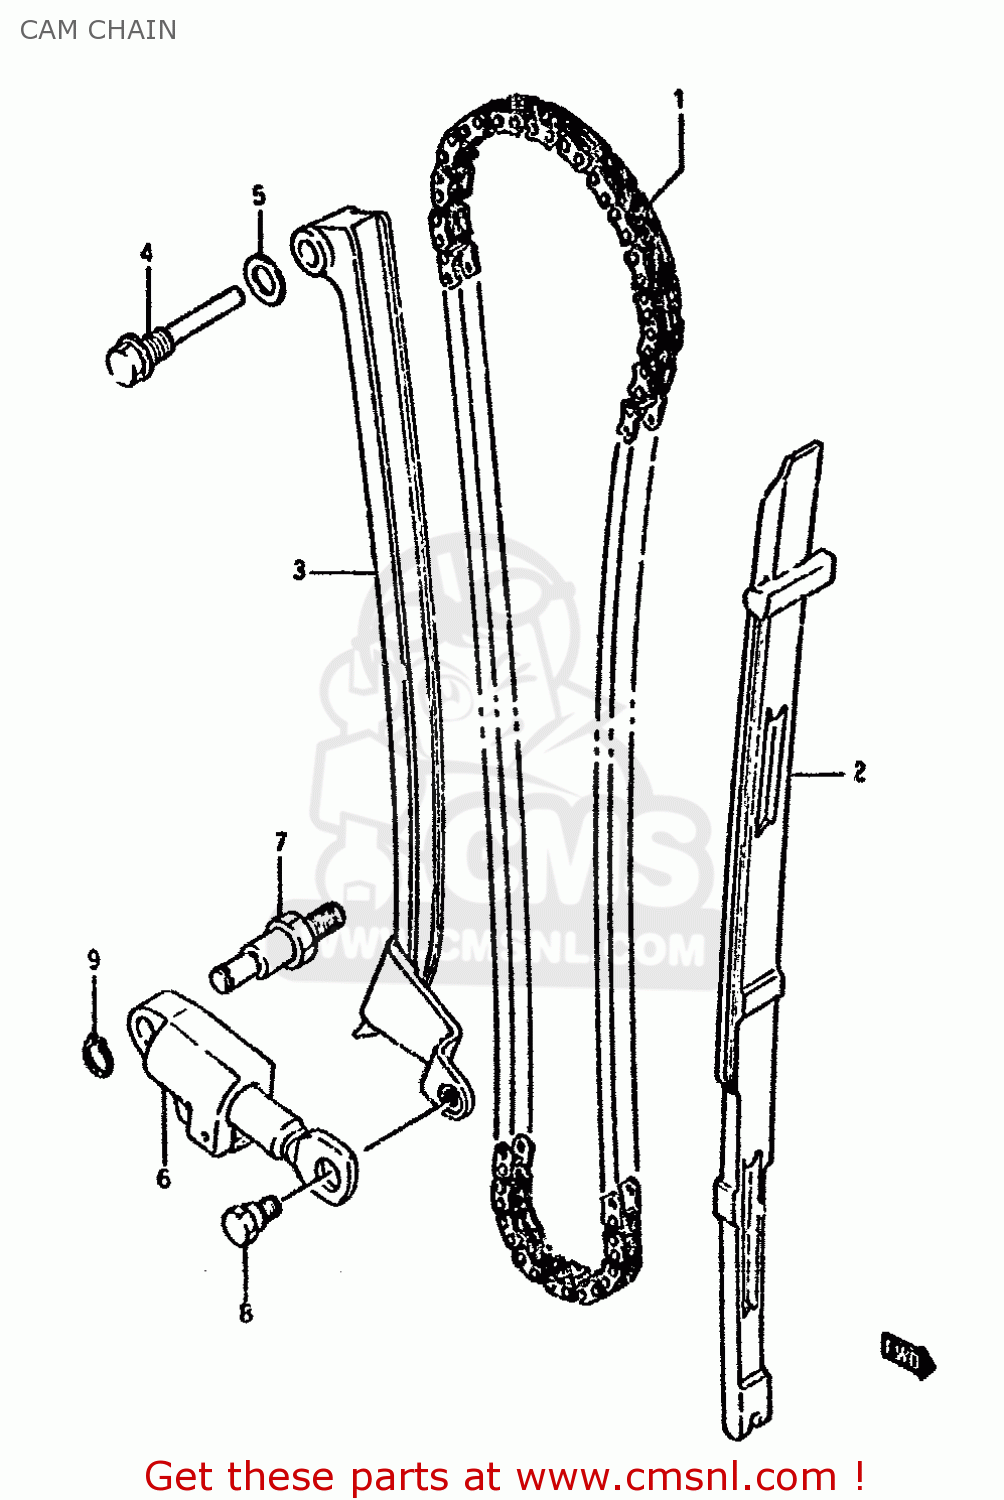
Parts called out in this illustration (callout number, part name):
1	CHAIN,CAMSHAFT DRIVE
2	GUIDE,CAM CHAIN
3	TENSIONER,CAM CHAIN
4	BOLT,CAM CHAIN TENSIONER
5	GASKET 8.2X14X1 (NAS)
6	ADJUSTER ASSEMBLY,TENSIONER
7	BOLT,STUD
8	BOLT
9	CIRCLIP
